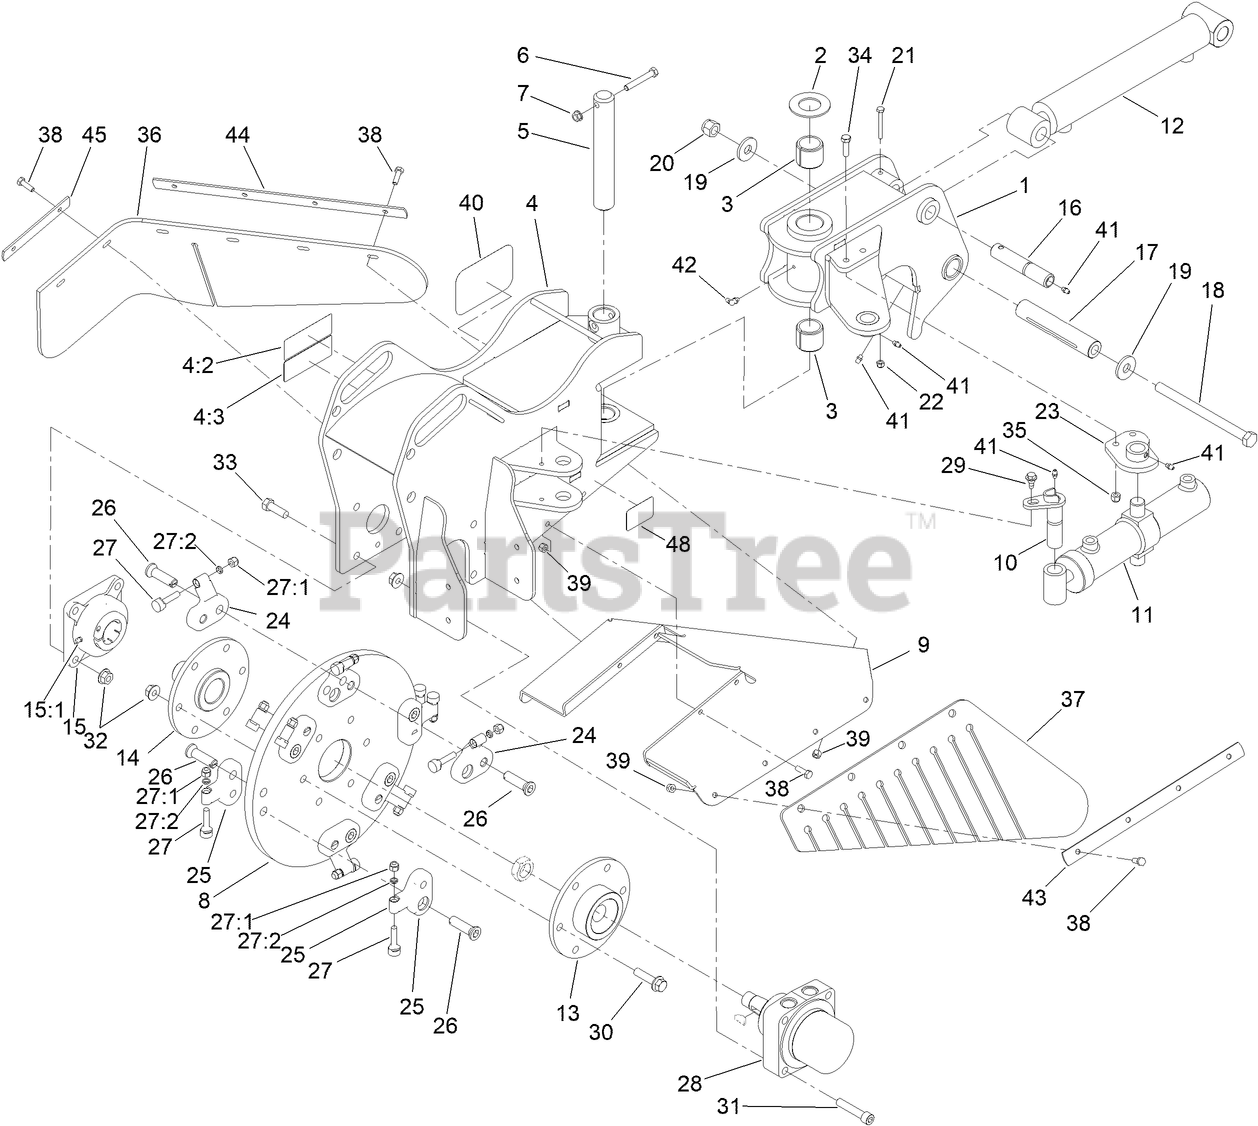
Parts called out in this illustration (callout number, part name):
2	WASHER
3	BUSHING-TENSION
4	FRAME ASM
4:2	DECAL-WARNING
4:3	DECAL-DANGER
5	PIN-PIVOT
6	SCREW-HH
7	NUT-HHF, WHIZ
8	WHEEL-CUTTER
9	GUARD-CHIP
10	PIN-PIVOT
11	HYD CYLINDER ASM
12	HYD CYLINDER ASM
13	HUB-DRIVE
14	SHAFT-STUB
15	BEARING
15:1	FITTING-GREASE
16	PIN-PIVOT
17	SPACER-PIVOT
18	BOLT-HH
19	WASHER-HARDENED
20	NUT-LOCK, NI
21	SCREW-HH
22	NUT-LOCK, NI
23	MOUNT-CYLINDER
24	POCKET-ANGLED
25	POCKET-STRAIGHT
26	BOLT-HSH, RH
27	GRINDER TOOTH ASM
27:1	NUT-LOCK, NI
27:2	SPACER-TOOTH
28	HYD MOTOR ASM
29	BOLT-SHOULDER
30	SCREW-HHF
31	SCREW-HSH
32	NUT-HHF
33	SCREW-HH
34	SCREW-HH
35	NUT-LOCK, NI
36	SHIELD-RUBBER, RH
37	SHIELD-RUBBER, LH
38	SCREW-HH
39	NUT-LOCK, NI
41	FITTING-GREASE
42	FITTING-GREASE, 90 DEG
43	STRAP-RETAINER, LH
44	STRAP-RETAINER, REAR
45	STRAP-RETAINER, RH
48	DECAL-LIFT/TIE DOWN
